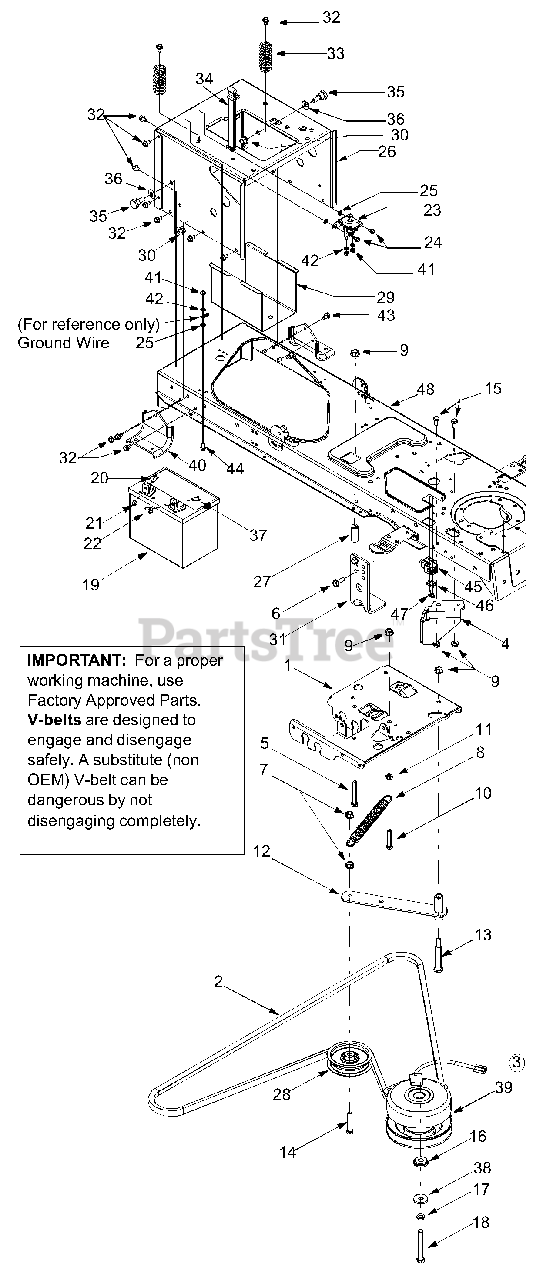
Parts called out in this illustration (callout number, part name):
2	PTO Belt
3	Elec. PTO Clutch (Mod. Z809K)
3	Washer, Flat, 1.031 x 1.62 x .095
6	Hex Hd Wash. Screw, 5/16-18 x .875
7	Flange Lock Nut, 3/8-16
8	Extension Spring, .62 x 5.62
9	Flange Lock Nut, 5/16-18
10	Hex Cap Screw, 5/16-18 x 1.75
11	Hex Nut, 5/16-18
12	Idler Bracket Assembly
13	Shoulder Screw, 1/2 x 2.5
14	Hex Cap Screw, 3/8-16 x 2.0
15	Hex Cap Screw, 5/16-18 x .625
16	Shoulder Spacer, 1.38 x .445 x .36
17	Lock Washer, 7/16
18	Hex Cap Screw, 7/16-20 x 3.25
19	12-volt Battery, 270 CCA
20	Hex Cap Screw, 1/4-20 x .62
21	Hex Sems Nut, 1/4-20
22	Wing Nut, 1/4-20
23	Solenoid, 12-Volt, 100 Amp
24	Self Tapping Screw, 1/4-20 x .5
25	Lock Washer, 1/4
28	Idler Pulley, 3.5
32	Self Tapping Screw, 5/16-18 x .625
33	Compression Spring, 1.28 x 3.5
34	Battery Strap
35	Shoulder Screw, .625 x .5, 7/16-20
36	Bell Washer, .45 x 1.0 x .062
37	Shoulder Screw, 1/4-20, .25 x .15
38	Flat Washer, .45 x 1.25 x .164
39	Harness Assembly, PTO Clutch
41	Hex Nut 1/4-20
42	Lock Washer
43	TT Screw 5/16-18 x 0.5
44	TT Screw 1/4-20 x 0.75
45	Switch
46	Switch Plate
47	AB Screw #10-16 x 0.5
